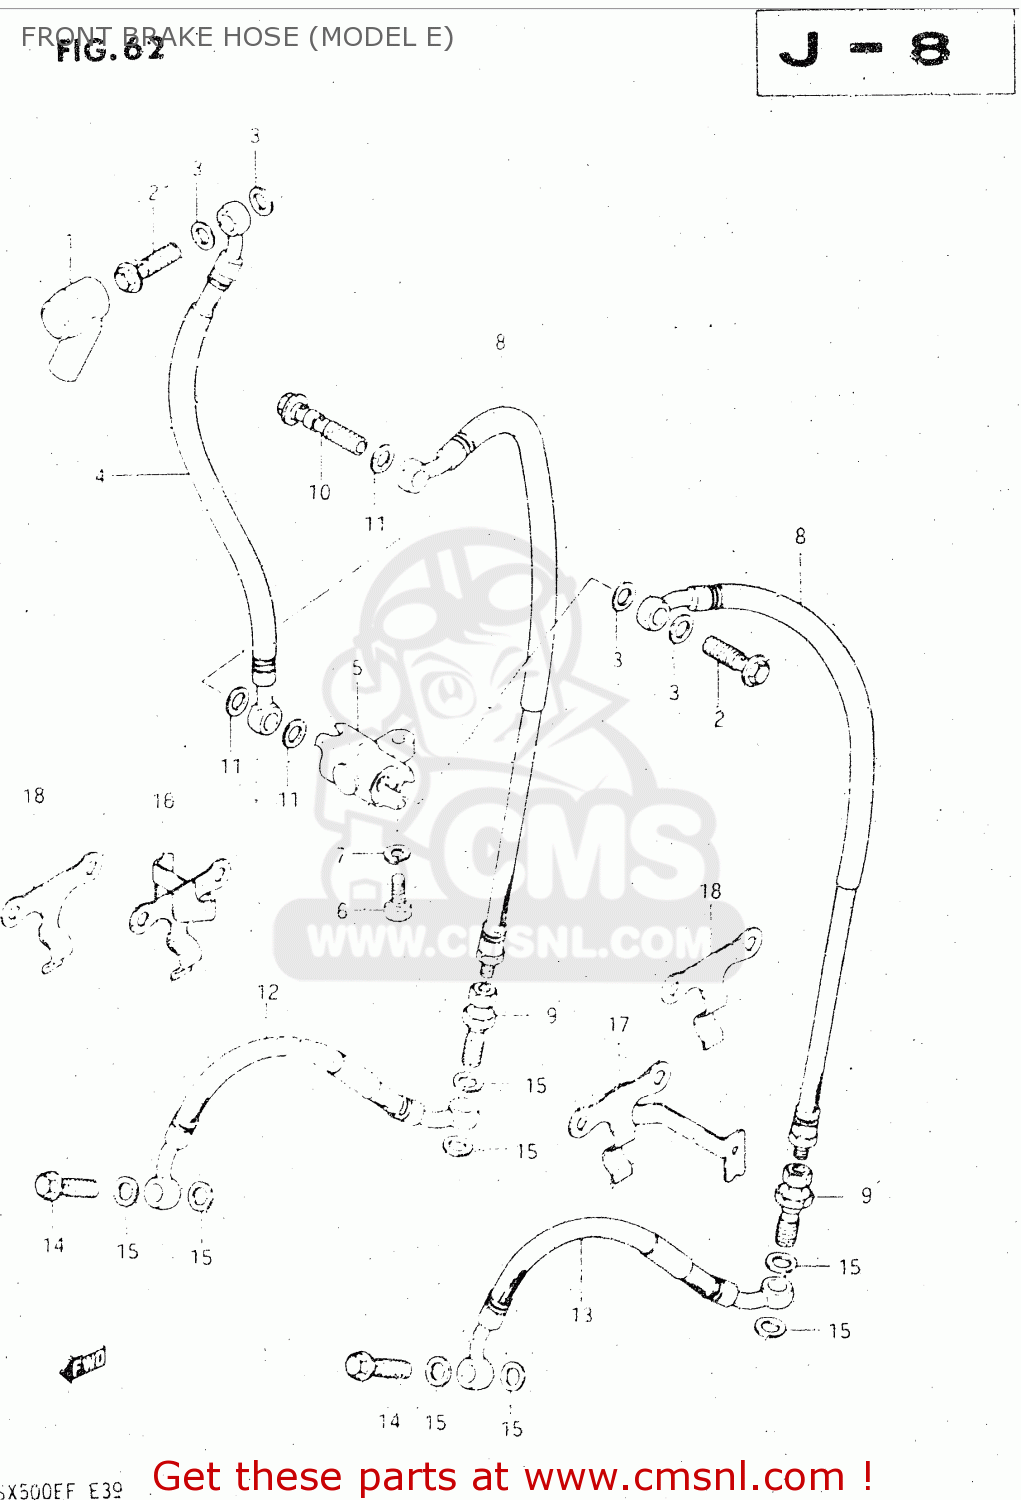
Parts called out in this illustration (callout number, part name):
1	BOOT,MASTER CYLINDER
2	BOLT UNION
3	WASHER(10X15X1.5)
4	HOSE,FRONT BRAKE
5	JOINT,BRAKE HOSE
6	BOLT
7	LOCK WASHER
8	HOSE,BRAKE NO.2
9	ADAPTER,BRAKE HOSE
10	BOLT,UNION
11	WASHER(10X15X1.5)
12	HOSE,ANTI-NOSE DIVE,RIGHT
13	HOSE,ANTI-NOSE DIVE,LEFT
14	BOLT UNION
15	WASHER(10X15X1.5)
16	CLAMP,FRONT BRAKE HOSE
17	CLAMP,FRONT BRAKE HOSE
18	CLAMP, HOSE
